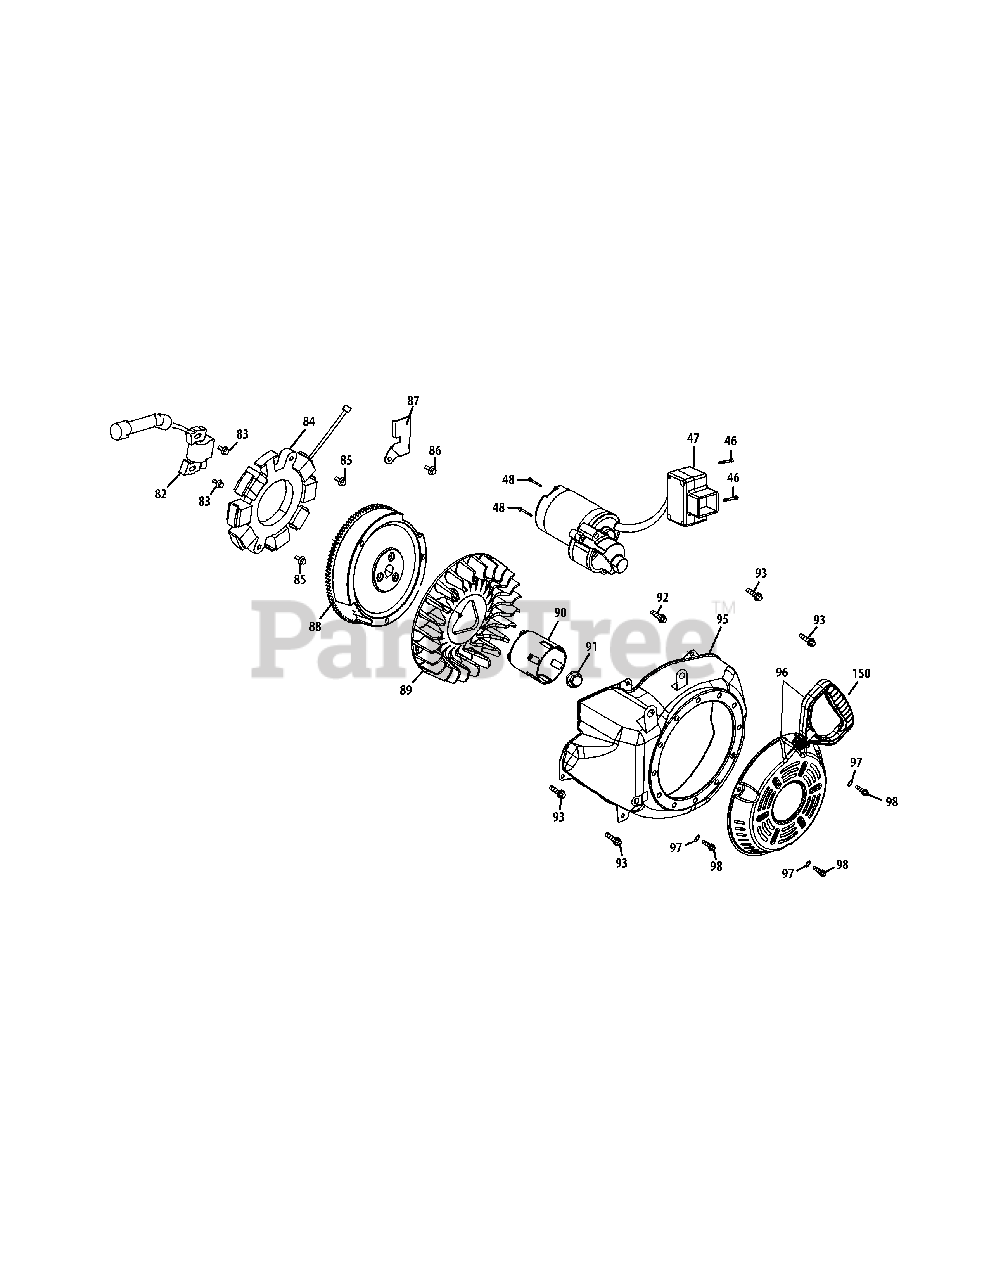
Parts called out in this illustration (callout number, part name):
46	Bolt M4×55
47	Electric Starter
48	Bolt M8×55
82	Ignition Coil Assembly
83	Ignition Coil Bolt
85	Bolt M6×30
86	Bolt M6×8
87	Alternator Wire Clamp Bracket
89	Fan, Cooling
90	Starter Cup
91	Nut, Special, M16×1.5
92	Bolt M6×16
93	Bolt M6×12
95	Blower Housing
96	Recoil Starter
97	Flat Washer - Recoil
98	Bolt M6×10
150	Starter Handle
